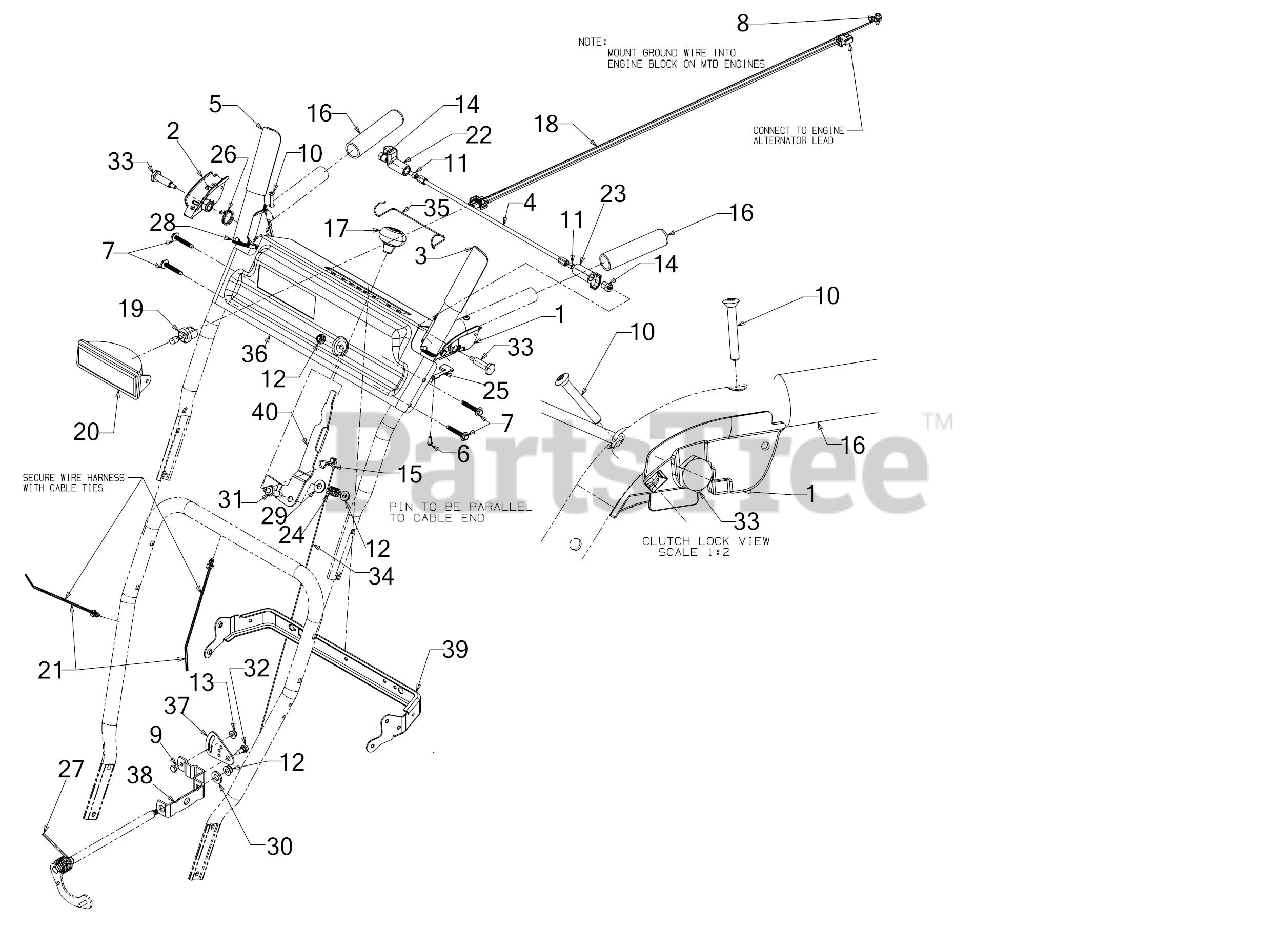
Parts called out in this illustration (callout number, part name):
1	CLUTCH LOCK HANDLE ASSEMBLY (LH)
2	CLUTCH LOCK HANDLE ASSEMBLY (RH)
3	HANDLE ASSEMBLY (LH)
4	PIVOT ROD
5	ENGAGEMENT HANDLE ASSEMBLY (RH) (BLACK)
6	SCREW #8-16 x .50
7	SCREW 1/4-20 x 1.625
8	SCREW 1/4-20 X.500
9	SCREW 1/4-20 x .620 GR5
10	SCREW #10-24 x 1.375
11	SCREW 1/4-20 x .50
12	FLANGE LOCK NUT 5/16-18
13	FLANGE LOCK NUT
14	HEX NUT W/PATCH
15	INTERNAL COTTER PIN
17	SHIFT KNOB
18	HARNESS
19	HALOGEN BULB
20	LAMP HOUSING
21	PUSH MOUNT TIE
22	LOCK PLATE
23	CLUTCH LOCK CAM
24	COMPRESSION SPRING
25	CLUTCH SPRING
26	TORSION SPRING
27	TORSION SPRING
28	RUBBER BUMPER
29	FLAT WASHER .385X.870X.090
30	FLAT WASHER
31	SHOULDER BOLT
32	SHOULDER SCREW
33	SHOULDER SCREW .437 x 1.345 1/4-20
34	SPEED SELECTOR CABLE (STEEL)
35	RETAINER
36	HANDLE PANEL:STEEL
37	PIVOT BRACKET
38	SHIFT SPEED BRACKET
39	HANDLE SUPPORT BRACKET
40	SPEED SHIFT LEVER
